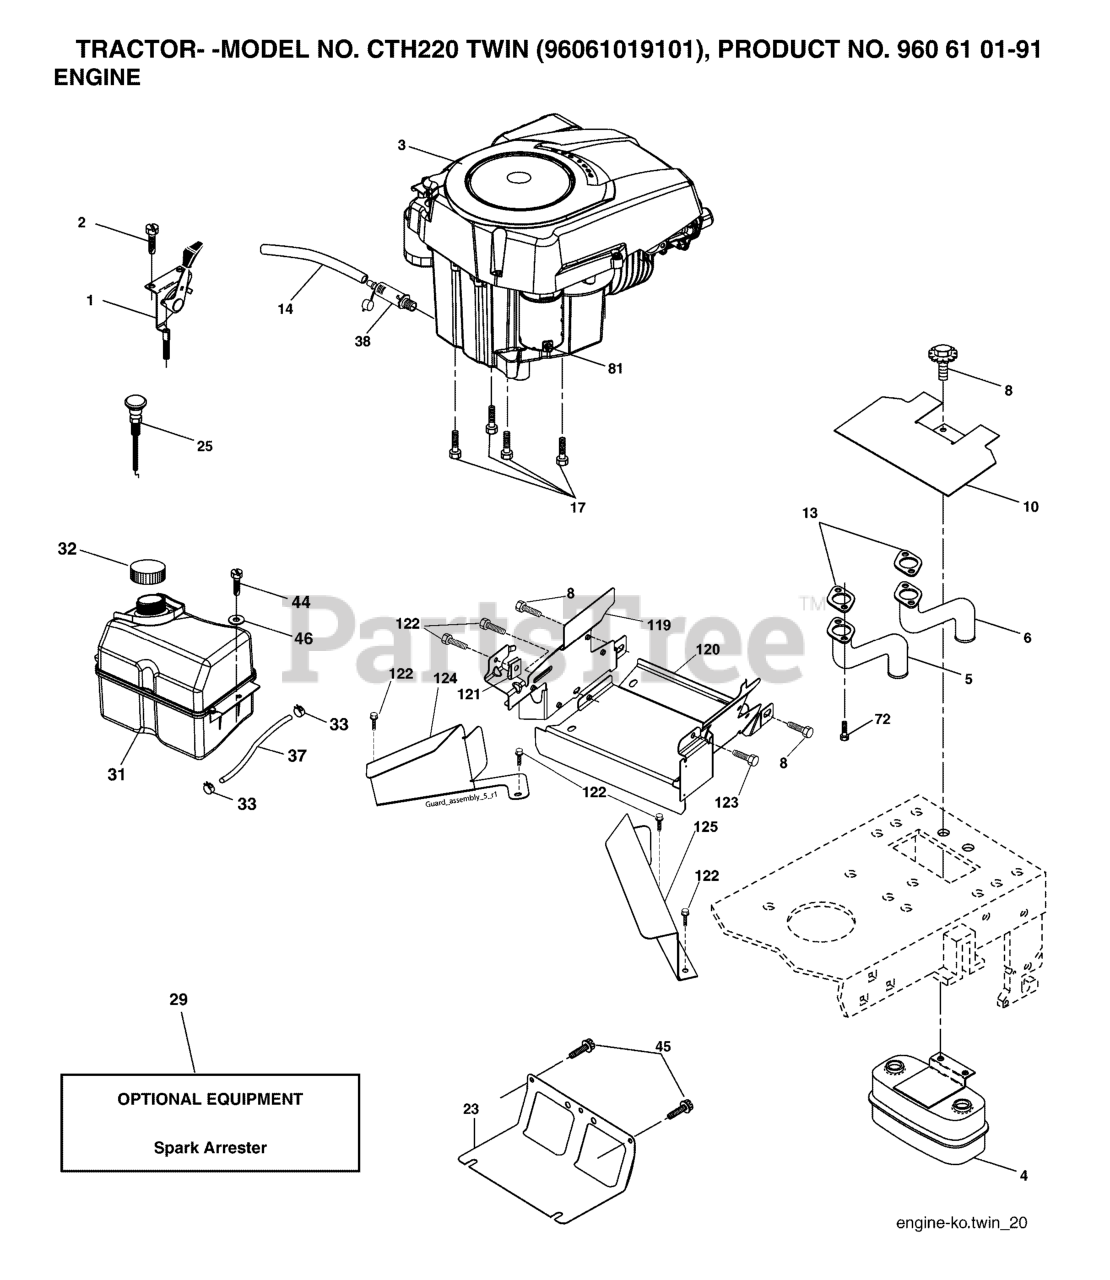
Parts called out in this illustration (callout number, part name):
1	THROTTLE CONTROL
2	SCREW
4	MUFFLER.TWIN.CYL.LOW.TONE
5	RP.PIPE-EXHAUST LH
6	RP.PIPE-EXHAUST RH
8	BOLT.5/16-18UNCX3/4 W/SEMS.BLK
10	RP SHIELD HEAT MUFFLER
14	TUBE, DRAIN OIL ASM.
17	SCREW 3/8-16X1
23	SHIELD.BROWNING.DBR.GUARD
25	CONTROL, CHOKE
29	KIT.SPARK ARRESTOR 794945 B&S
31	TANK.ASM.FUEL.FR.2.5GA.
32	FUEL CAP
33	HOSE CLAMP
37	LINE.FUEL.20
38	PLUG DRAIN OIL EASY
44	SCREW HEXWSHR 1/4-20X3/4
45	SCREW, 3/8-16X3/4
72	SCREW.SOCKET HD.5/16-1
81	NUT
119	LENKRAD
120	GUARD 532199767
122	SCREW.1/4-20X5/8
123	SCREW, 5/16-18 X 1/2
